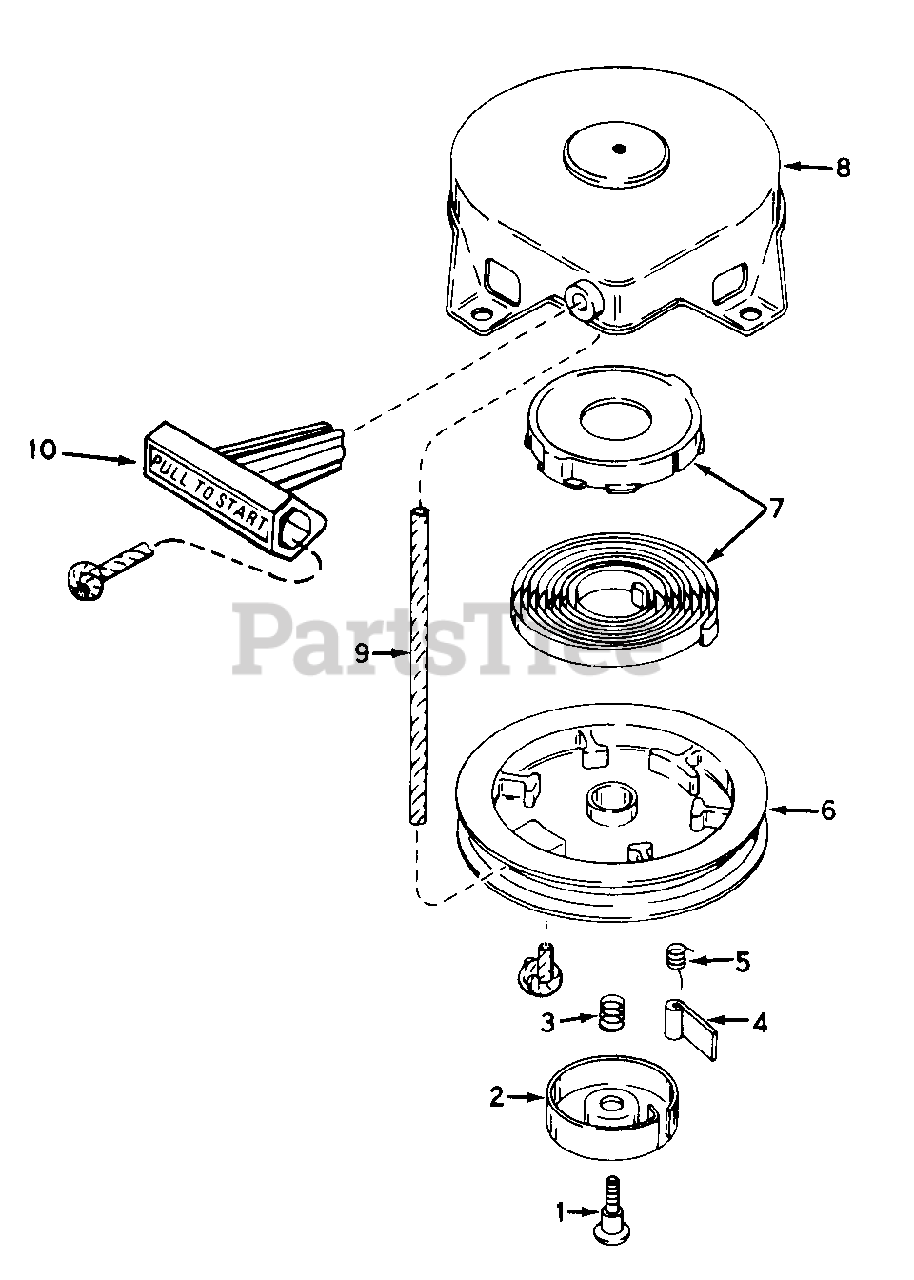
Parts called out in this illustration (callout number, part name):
1	Screw, Retainer
2	Retainer, R.H.
3	Spring, Brake
4	Dog, Starter
5	Spring, R.H. Dog
7	Spring & Keeper Ass'y.
8	Housing Ass'y., Starter
9	Rope, Starter
10	Handle Ass'y., Starter
